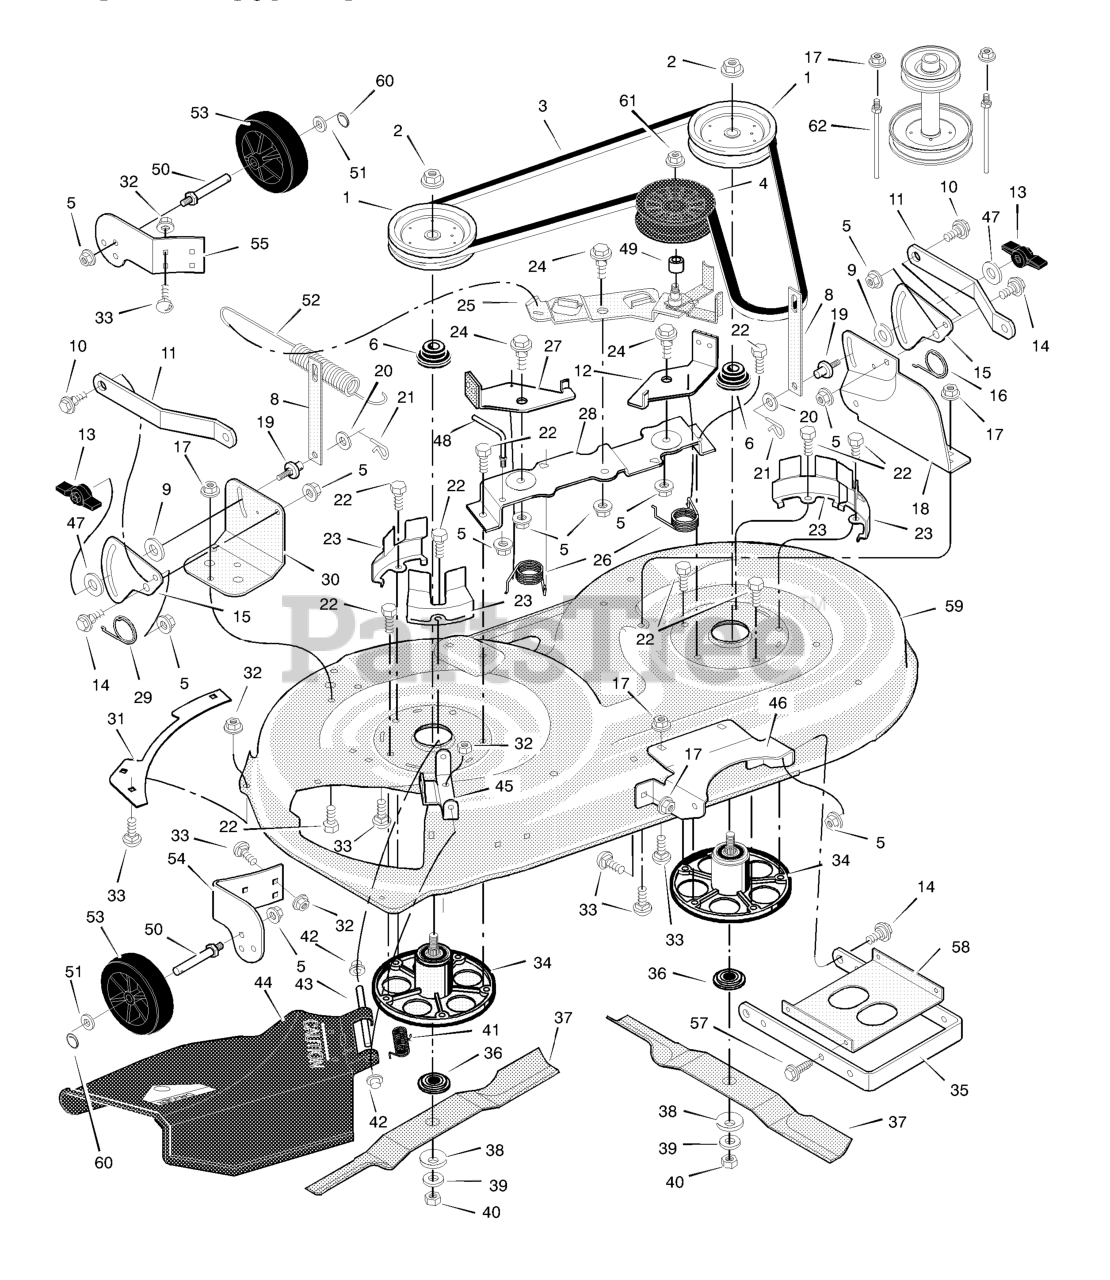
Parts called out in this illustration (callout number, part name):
1	Pulley, Jackshaft
2	Nut, Hex
3	Belt, Mower Drive
4	Pulley, Idler
5	Nut, Flange
6	Spacer, Pulley
8	Link, Lift
9	Pad, Friction
10	Bolt, Shoulder
11	Bracket, Suspension
12	Pad Assembly, Left Brake
13	Knob
14	Bolt, Shoulder
15	Plate, Suspension
17	Nut, Flange
18	Bracket, Suspension
19	Pin, Hanger
21	Pin, Hair
22	Bolt
23	Cover, Pulley
24	Bolt, Shoulder
25	Arm, Idler
27	Pad Assembly, Right Brake
28	Bracket, Brake
30	Bracket, Suspension
32	Nut, Flange
33	Bolt, Carriage
34	Mandrell Housing
35	Bracket, Suspension
36	Adapter, Blade
42	Cap, Push On
43	ROD, Deflector
44	Deflector Assembly
45	Bracket, Deflector Hinge
46	Bracket, Front Hanger
48	Guide, Belt
50	BOLT, Gauge Wheel
52	Spring, Extension
53	Wheel, Gage
54	Bracket, Right Wheel
55	Bracket, Left Wheel
58	Stiffener
59	Housing, Blade
60	Ring, Locking
61	Nut, Flange
62	Guide, Belt
